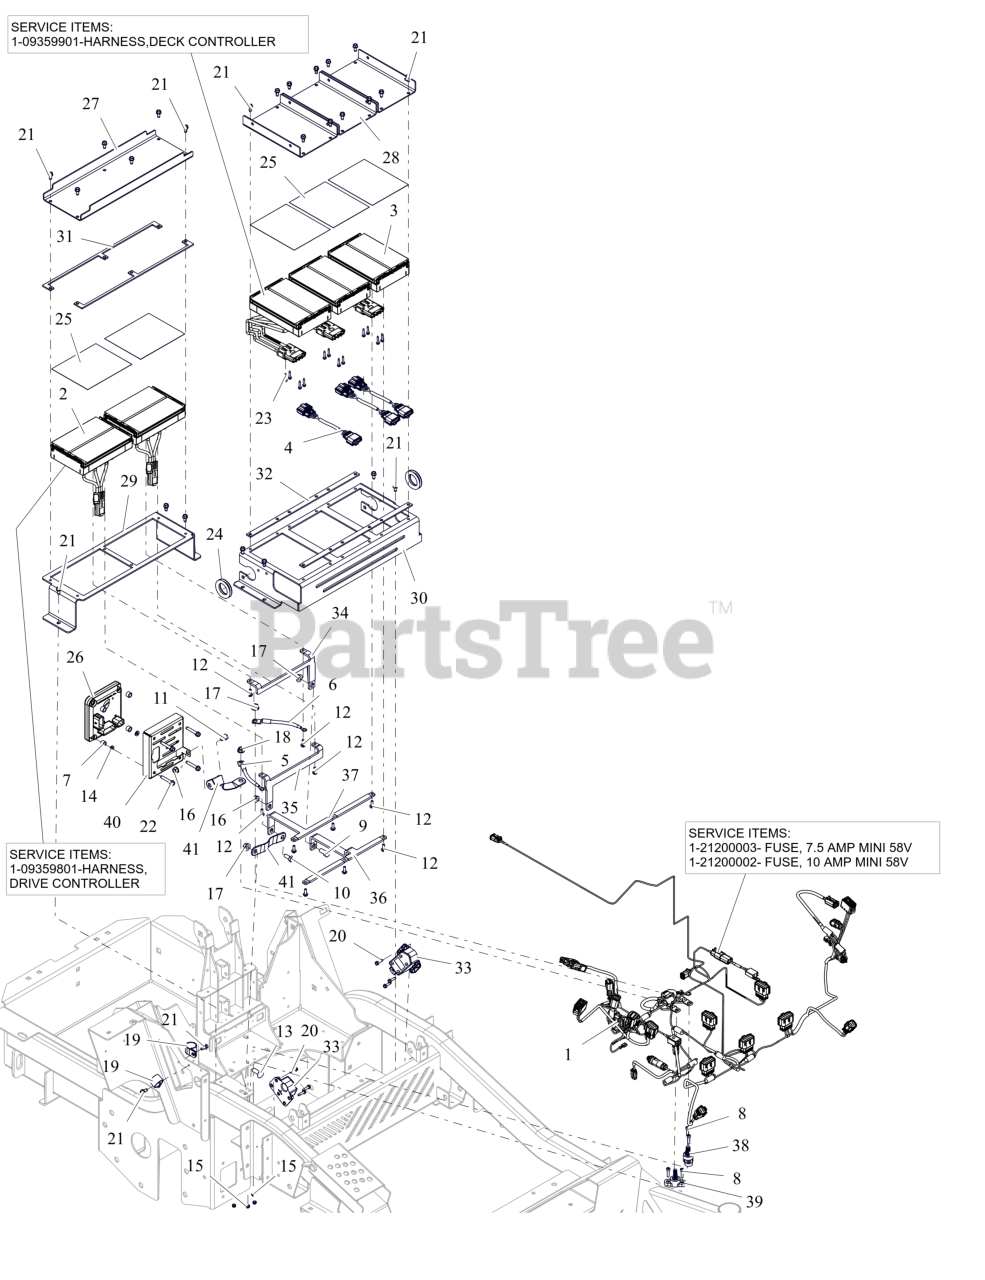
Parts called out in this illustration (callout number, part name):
1	HARNESS, ELECTRICAL - PT-EV
1	FUSE, 7.5 AMP MINI 58V
1	FUSE, 10 AMP MINI 58V
1	DIODE, CONNECTOR SHELL
2	ASM, DRIVE CONTROLLER W-HARNESS
3	ASM, DECK CONTROLLER W-HARNESS
4	HARNESS, DECK CNTRL JUMPER
5	CABLE, GROUND
6	CABLE, POSITIVE
7	SPCR, .334X.500X.324
8	SCR, SKH M5-.8X20 12.9ZC120
9	BLT,HEX .38-16X.75 G5 ZCC
10	BLT,HEX .31-18X.75 G5 ZCC
11	BLT, HEX .31-18X.50 GR5 ZCC
12	BLT,HEX M5-.8X16 EP30 G8.8 ZCC
13	BLT,RHSSN .38-16X1.00 G5 ZCC
14	WSHR,FLT .265X.500X.087 ZCC
15	NUT,NYL M5-.8 G8.8 ZCC
16	NUT,LK-CTR-FLG .31-18 GF ZCC
17	NUT-LK-CTR-FLG .375-16 GF ZCC
18	NUT, LK-NYL-FLG .31-18 GR5 ZC120
19	CLAMP, COUSHIONED STEEL REV
20	SCR, TAP #10-24X.75 HWH ZCC
21	SCR-TAP .25-20X.50 HWH ZCC
22	SCR-TAP .25-20X1.50 HWH ZCC
23	SCR-TAP #6-32X.75 HWH ZCC
24	GROMMET 1.25ID X 1.5OD
25	PAD, THERMAL
26	MODULE, VEHICLE CONTROL, SD PTEV
27	PLATE, HEAT SINK-REAR
28	PLATE, HEAT SINK-FRONT
29	MOUNT, CNTRL -DRIVE (BLACK)
30	MOUNT, CONTROLLER PLATE-FRONT (BLACK)
31	SPCR, HEAT SINK (BLACK)
32	SPCR, HEAT SINK - FRONT (BLACK)
33	SENSOR, STEERING
34	BAR, BUSS -POS. WHL
35	BAR, BUSS-NEG. WHL
36	BAR, BUSS-POS
37	BAR, BUSS -NEG
38	STUD, POSITIVE POWER
39	STUD, NEGATIVE POWER
40	COVER, VCMA ALUMINUM
41	STRAP, GROUND
